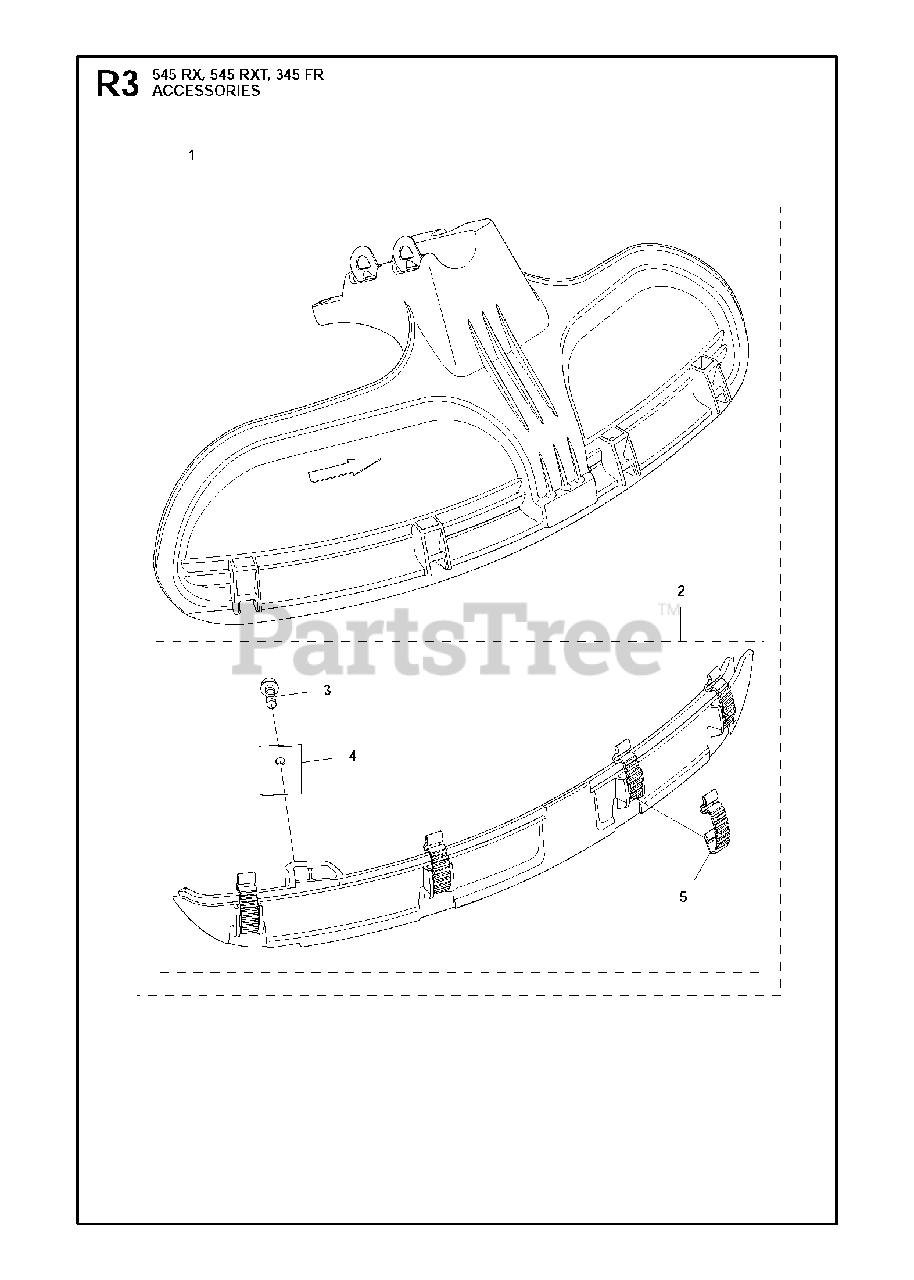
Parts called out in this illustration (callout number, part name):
1	COMBINATION GUARD
2	SPLASH GUARD
3	SCREW
4	LINE CUTTER
5	BUCKLE
